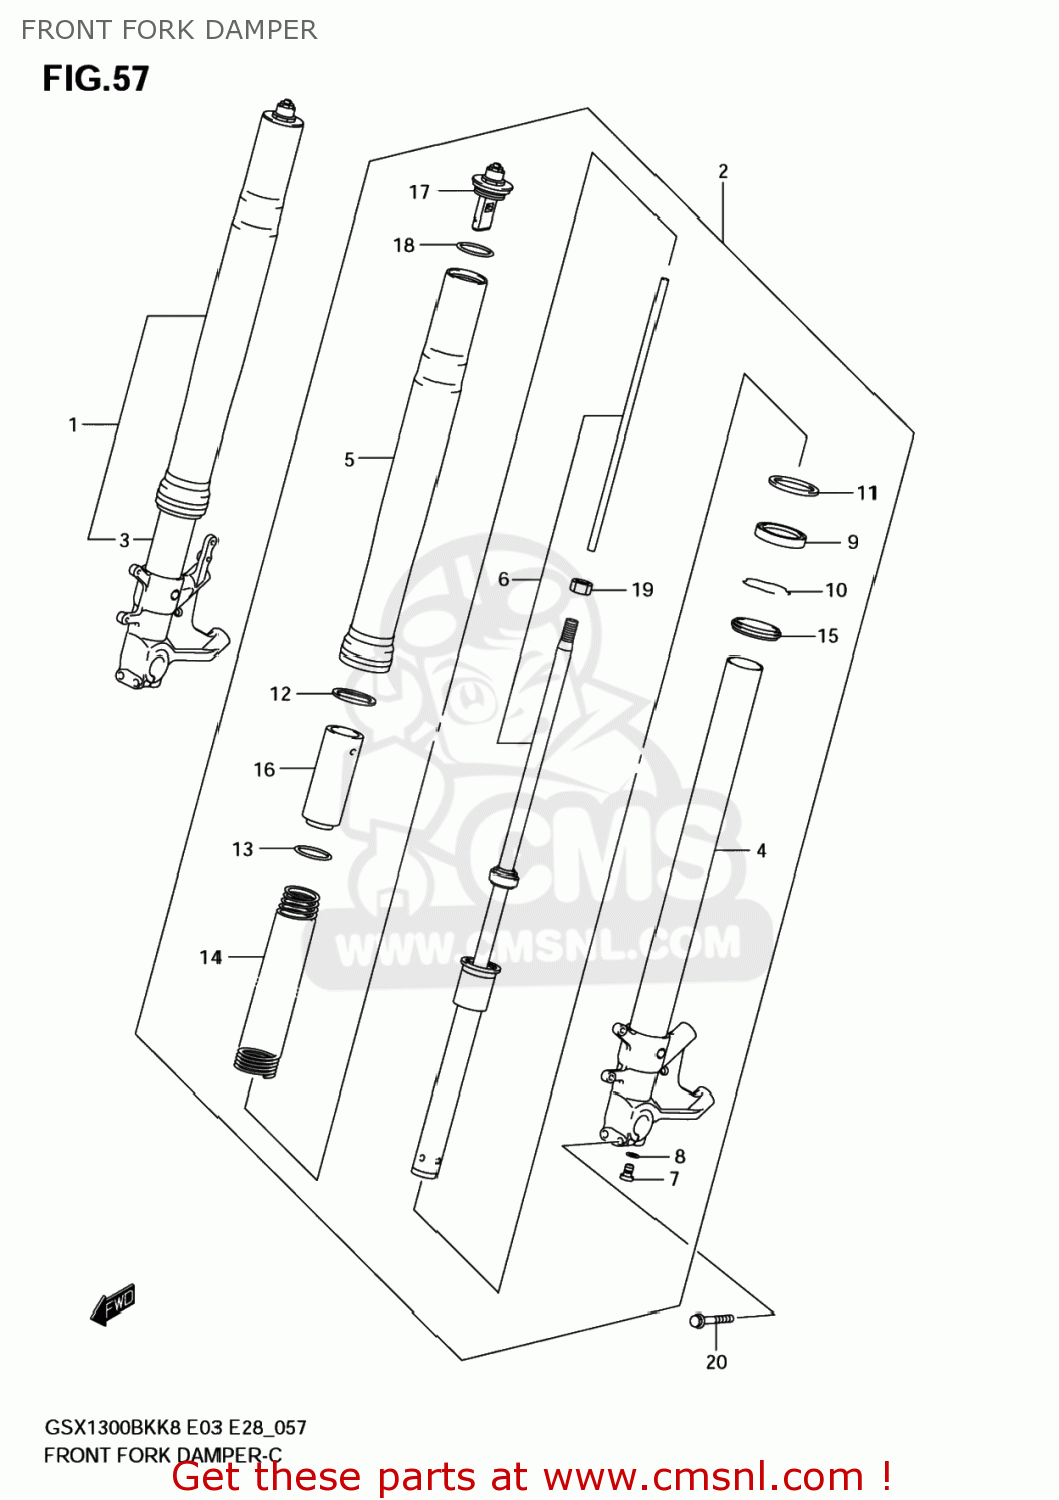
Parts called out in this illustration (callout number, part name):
1	DAMPER ASSY,FR FORK,R
2	DAMPER ASSY,FR FORK,L
3	TUBE,INNER,R
4	TUBE,INNER,L
5	TUBE,OUTER
6	CYLINDER
7	BOLT
8	GASKET (NAS)
9	SEAL,OIL
10	RING,STOPPER
11	WASHER
12	GUIDE,SPRING
13	WASHER
14	SPRING,FR
15	SEAL,DUST
16	SPACER,SPRING
17	CAP
18	O RING
19	NUT,ROD
20	BOLT
